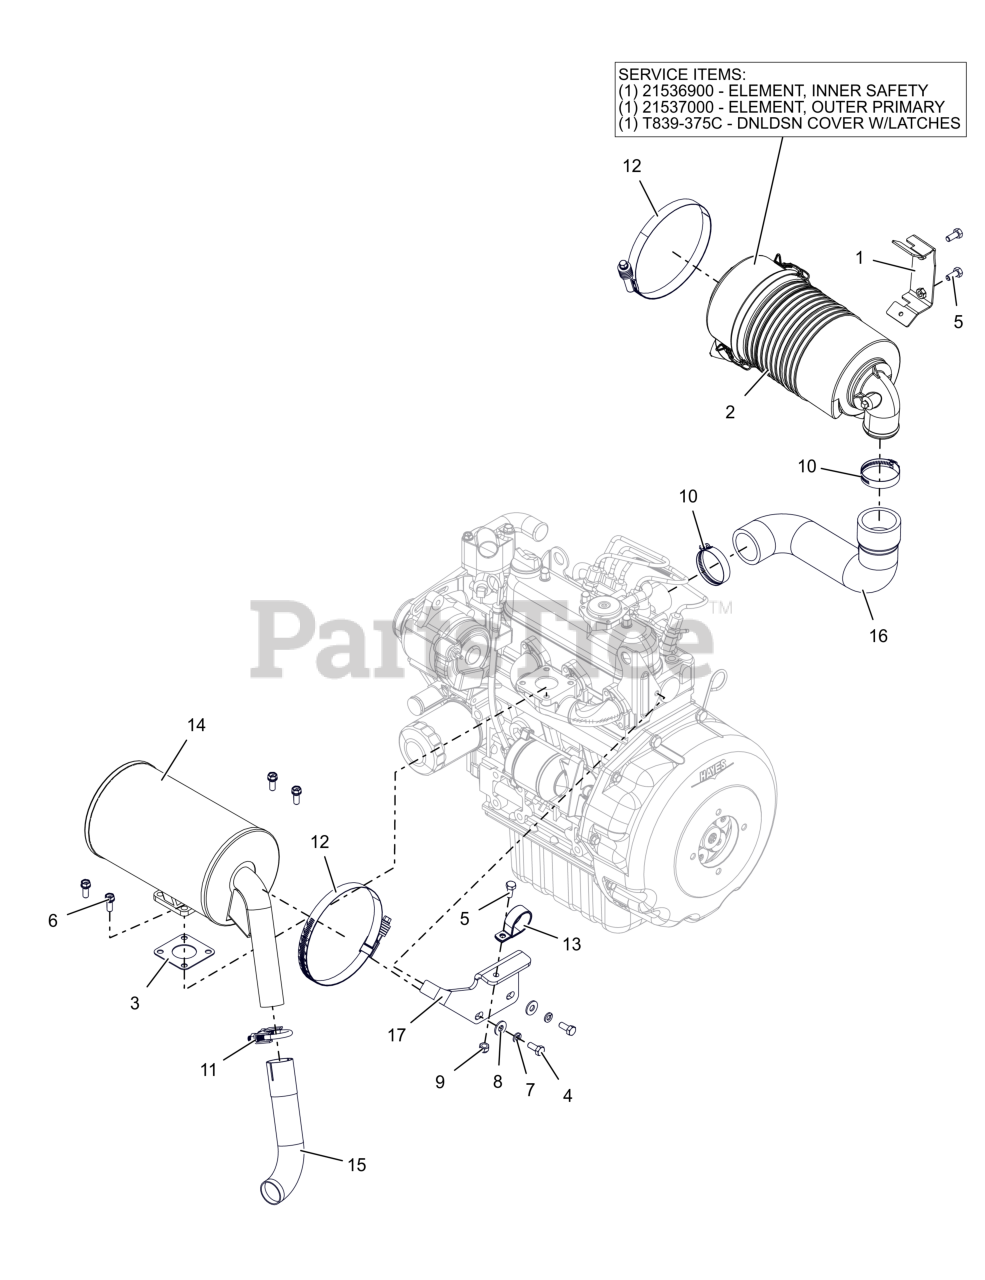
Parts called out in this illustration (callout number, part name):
1	WLDMT, MOUNT - AIR CLEANER (BLACK)
2	CLEANER, AIR
2	ELEMENT, INNER SAFETY
2	ELEMENT, OUTER PRIMARY
2	DNLDSN COVER W/LATCHES P533761
3	GASKET, MUFFLER - KUBOTA D1105
4	BLT, HEX M8-1.25X20 G8.8 ZCC
5	BLT,HEX .31-18X.75 G5 ZCC
6	BLT, UPSET M8-1.25X22 LCK WSHR
7	WSHR,LK-REG .312X.078 ZCC
8	WSHR,FLT .375X.875X.083 ZCC
9	NUT,NYL .31-18 G5 ZCC
10	CLAMP, HOSE #36 SS 1.813-2.75
11	CLAMP, MUFFLER-1.375 ZCC
12	CLAMP, TENSION - CONSTANT SAE662
13	CLAMP, CUSHIONED 1.375 x .344
14	MUFFLER, KUBOTA - D1105
15	PIPE, EXHAUST
16	HOSE, AIR CLEANER 1.75-2.00
17	BRKT, MUFFLER SUPPORT (BLACK)
